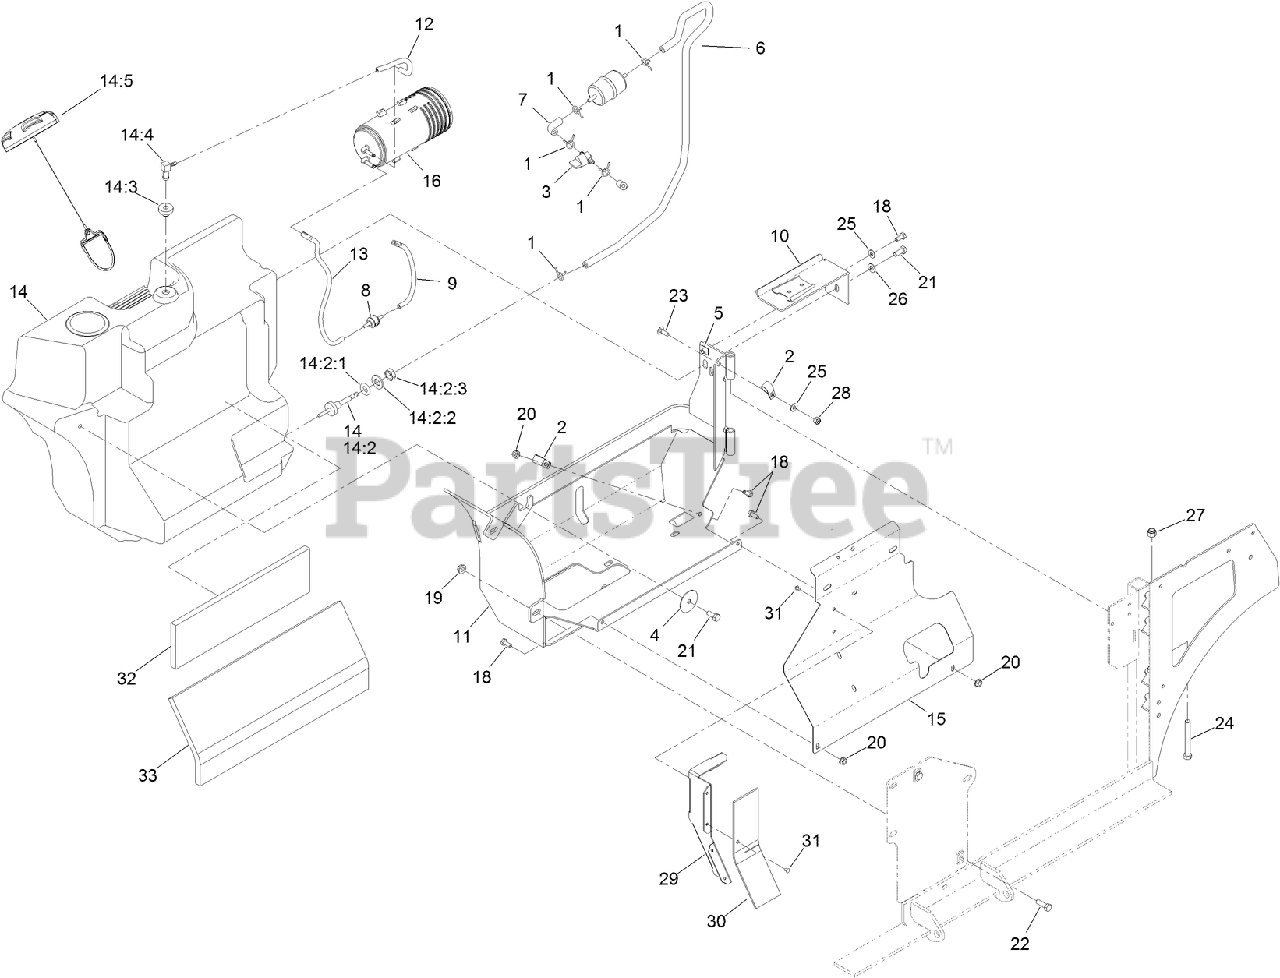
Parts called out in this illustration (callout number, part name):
2	CLIP-LOOM
3	VALVE-FUEL
4	WASHER
6	FUEL LINE ASM
7	HOSE-FUEL
8	VALVE-CHECK, VACUUM
9	HOSE-VENT, FORMED
10	CANISTER BRACKET ASM
11	TANK FRAME ASM
12	HOSE-VENT, FORMED
13	HOSE-VENT, FORMED
14	FUEL TANK ASM
14:2	FITTING-FUEL, BULKHEAD
14:2:1	O-Ring
14:2:2	WASHER-FLAT
14:2:3	NUT-JAM
14:3	BUSHING
14:4	FITTING-90 DEG
14:5	CAP-FUEL, RATCHETING
15	PANEL-TANK SHIELD
16	CANISTER-CARBON, 800CC
18	SCREW-HH
19	NUT-HF
20	NUT-HF
21	SCREW-HH
22	SCREW-HH
23	BOLT-CARR
24	SCREW-HH
25	WASHER-FLAT
26	WASHER-PLAIN
27	NUT-LOCK, NI
28	NUT-LOCK, NI
29	DEFLECTOR-AIR
30	FLAP-RUBBER
31	RIVET-POP
32	INSULATION-FOAM PAD, FRONT
33	INSULATION-FOAM PAD, REAR
